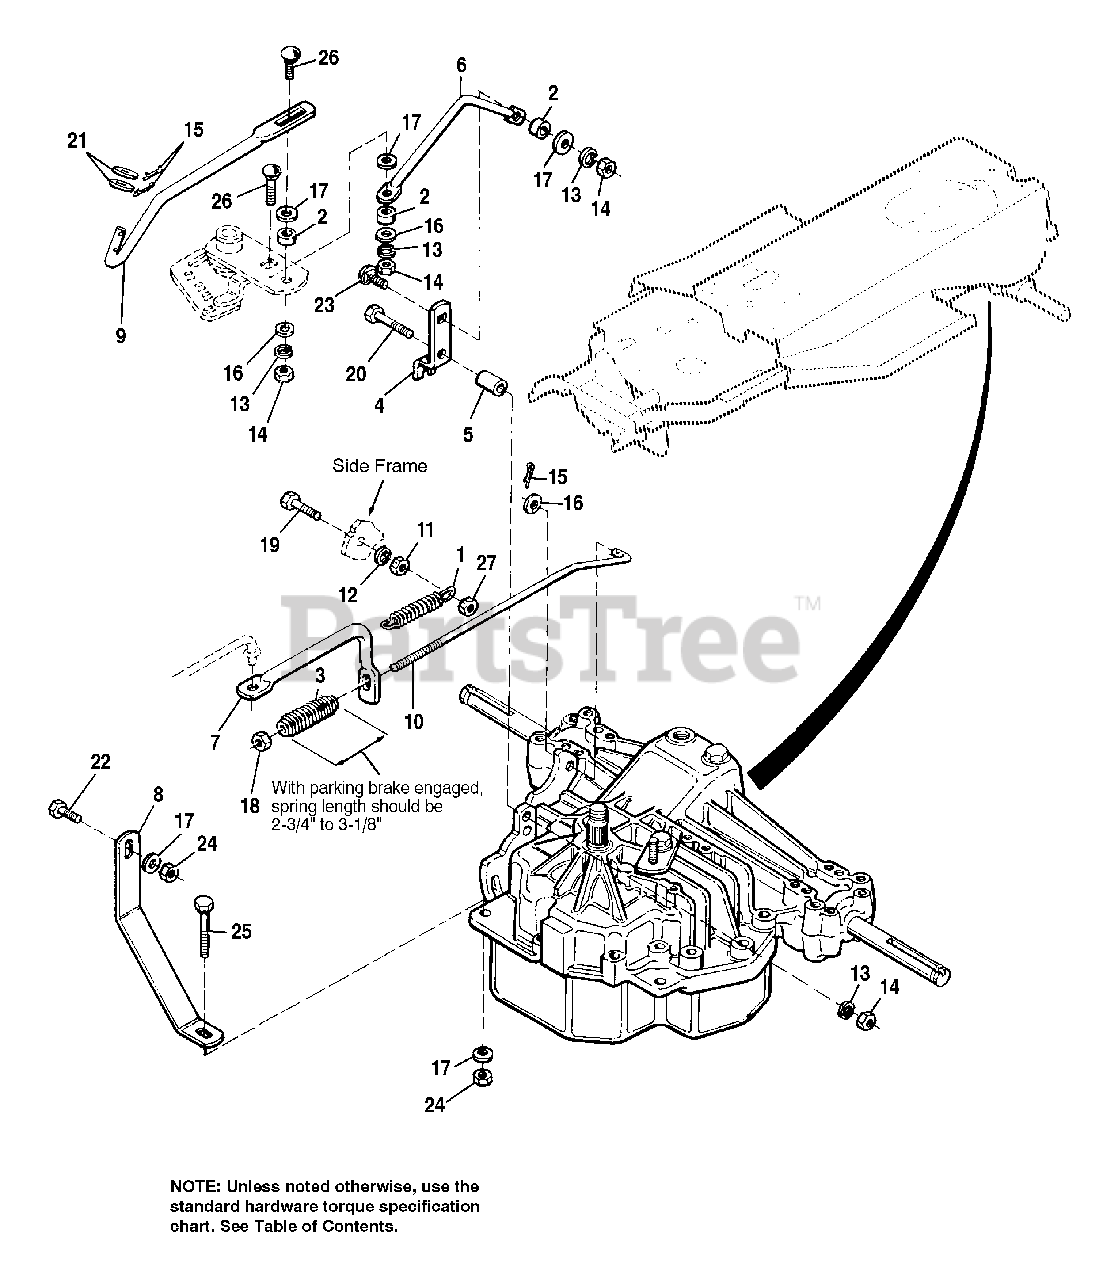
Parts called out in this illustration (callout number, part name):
1	SPRING, Brake Arm
4	LEVER, Control
6	ROD, Shift, Rear
8	TORQUE STRAP
9	ROD, Shift, Front
11	NUT, Hex, Full, 3/8-16
12	LOCKWASHER, 3/8
13	LOCKWASHER, 5/16
14	NUT, Hex, Full, 5/16-18
15	COTTER PIN
16	WASHER, Plain, 5/16
17	WASHER, 11/32 x 1 x 1/8
18	NUT, Hex, Nylon Lock, 5/16-18
19	CAPSCREW, Hex, 3/8-16 x 1-1/4
20	CAPSCREW, Hex, 5/16-18 x 1-3/4
21	WASHER, 17/32 x 1-1/4 x 5/64
22	SCREW, Hex, Whizlock, 5/16-18 x 3/4
23	CARRIAGE BOLT, 5/16-18 x 1
24	NUT, Hex, Flange, Lock, 5/16-18
25	SCREW, Hex, Whizlock, 5/16-18 x 2-1/4
26	CARRIAGE BOLT, 5/16-18 x 1-1/4
27	JAMNUT, Hex, Lock, 3/8-16
